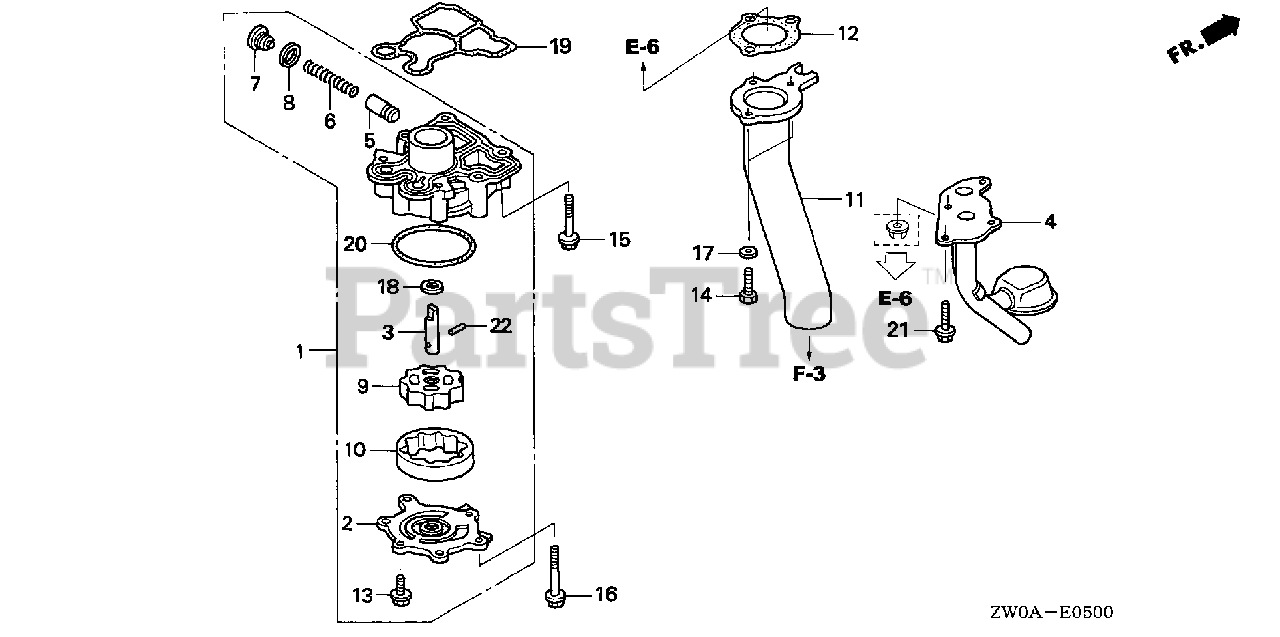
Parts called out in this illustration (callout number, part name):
1	PUMP ASSY., OIL
2	COVER, OIL PUMP
3	SHAFT, OIL PUMP
4	STRAINER, OIL
5	VALVE, RELIEF
6	SPRING, RELIEF VALVE
7	BOLT, SEALING (18MM)
8	WASHER, SEALING (18MM)
9	ROTOR (INNER)
10	ROTOR (OUTER)
12	GASKET, EX. PIPE
13	BOLT, FLANGE (6X18) (CT200)
14	BOLT, HEX. (8X25)
15	BOLT, FLANGE (8X40)
16	BOLT, FLANGE (8X65)
17	WASHER, PLAIN (8MM)
18	WASHER, THRUST (13MM)
19	O-RING, OIL PUMP
20	O-RING, PUMP COVER
21	BOLT, FLANGE (8X20)
22	ROLLER (5X17.8)
